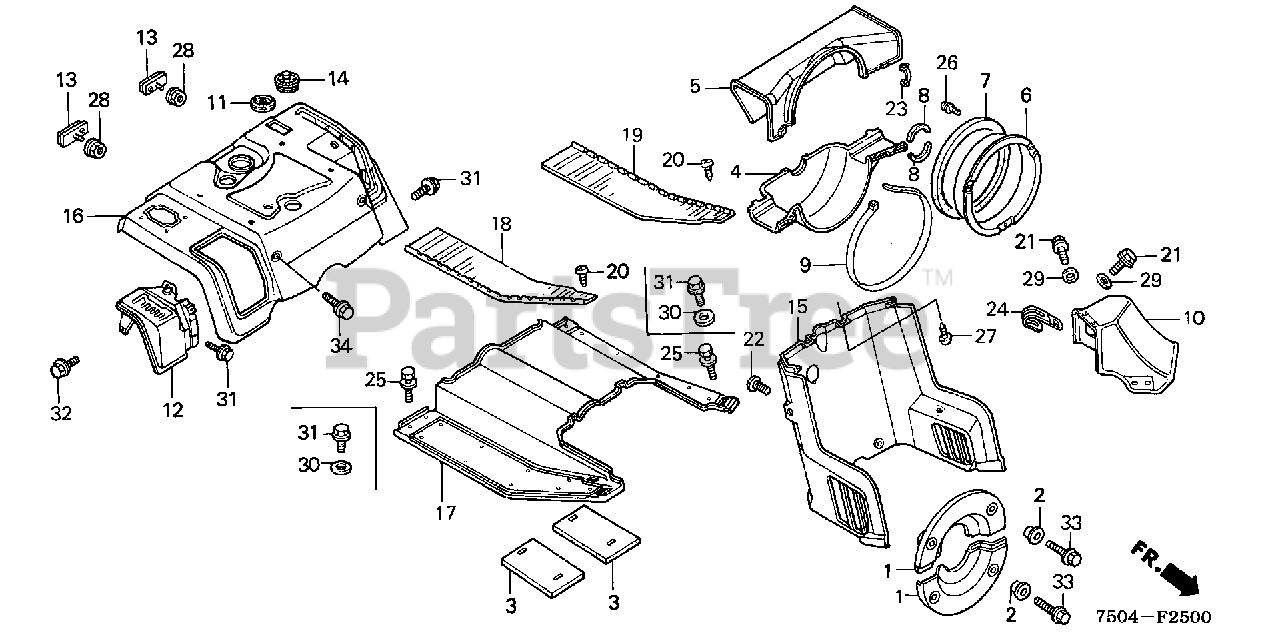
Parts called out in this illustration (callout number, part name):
1	COVER, DUST
2	COLLAR, DUST COVER
9	BAND (650MM)
11	GROMMET, WIRE
12	GUIDE, CHANGE LEVER *R136* (DIANA RED) (NOT AVAILABLE)
13	REFLECTOR, REFLEX
15	SHELL, COMPARTMENT *NH105* (MAT BLACK)
16	FENDER, RR. *R136* (DIANA RED) (NOT AVAILABLE)
17	FLOOR *R136* (DIANA RED)
18	FLOOR MAT, R.
19	FLOOR MAT, L.
20	SCREW, TAPPING (4X14)
22	SCREW, METER VISOR SETTING
27	SCREW, TAPPING (6X16)
28	NUT, FLANGE (5MM)
30	WASHER, PLAIN (6MM)
31	BOLT, FLANGE (6X12)
32	BOLT, FLANGE (6X12)
33	BOLT, FLANGE (6X20)
34	BOLT, FLANGE (8X16)
